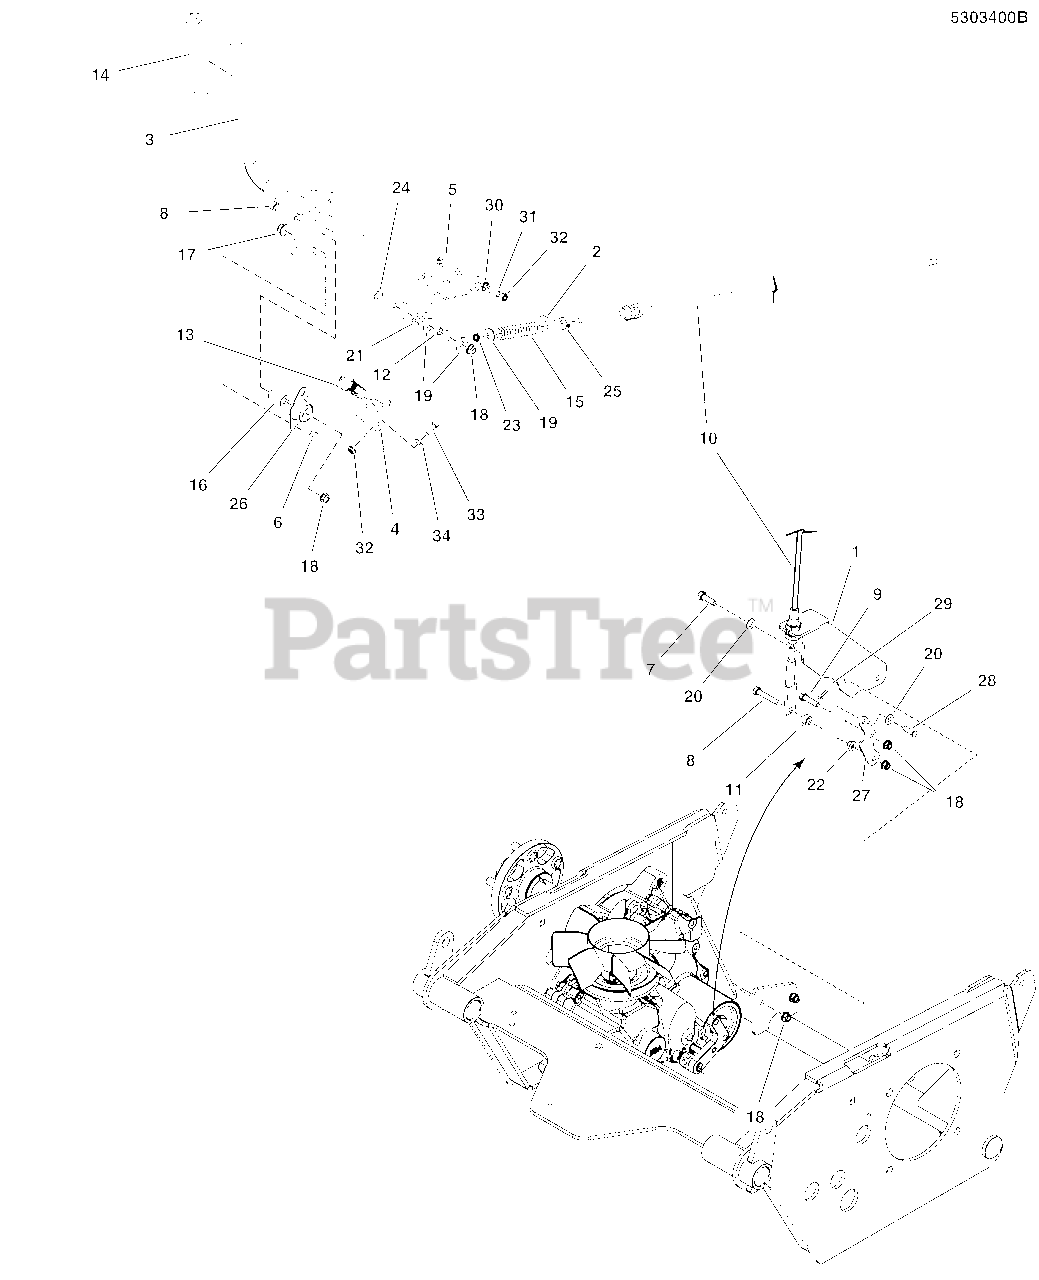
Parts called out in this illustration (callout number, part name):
1	BRACKET, Mounting
2	ARM, Link
3	WELD, BRAKE SHAFT, LOCTOUT, 17" - BLK
4	TAB, SWITCH PLATE, BOLT-ON - BLK
5	BOLT, 1/4-20 X 1.500, GR5, SQ, ZINC/CLEA
6	BOLT, 3/8-16 X 3/4" GD5 CZ
7	BOLT, 5/16-18 X 1 GD5 CZ
8	BOLT, 5/16-18 X 1-3/4 GD5 CZ
9	BOLT, 5/16-18 X 1-1/4 GD5 CZ
10	CABLE, PARKING BRAKE, 32"
11	SPACER, .33 X .63 X .36, PM, CZ
12	SPACER, .33 X .50 X .25, PM, CZ
13	SWITCH, DP NO/NC SNAP-IN
14	GRIP, FOAM, 3/4 ID X 6 X .187
15	SPRING, COMP. 1/2 ID X .140 WIRE X 3.25
16	SPACER, .32 X .75 X 1.06, PM
17	NUT, 3/8-16 HEX NYLOCK FLANGE
18	NUT, 5/16-18 HEX NYLOCK FLANGE
19	WASHER, 5/16 USS
20	WASHER, 5/16" SAE
21	NUT, 5/16-18 HEX SERRATED FLANGE (LARGE)
22	NUT, 5/16-18 HEX SERRATED FLANGE (SMALL)
23	NUT, 5/16-24 HEX NYLON LOCK
24	BOLT, 5/16-18 X 1 1/2 FLANGE
25	COLLAR, 5/16 SET
26	BEARING, 3/4" FLANGED, BRONZE
27	PLATE, BRAKE ARM, IS2100 - BLK
28	PIN, CLEVIS, 5/16 X 1, PLATED
29	PIN, COTTER, 1/8 X 3/4
30	NUT, 1/4-20 HEX SERR. FLANGE
31	SPACER, .25 X .38 X .63, CZ
32	NUT, 1/4-20 HEX NYLON LOCK
33	BOLT, 1/4-20 X 3/4 GD5 CZ
34	WASHER, 1/4 SAE
